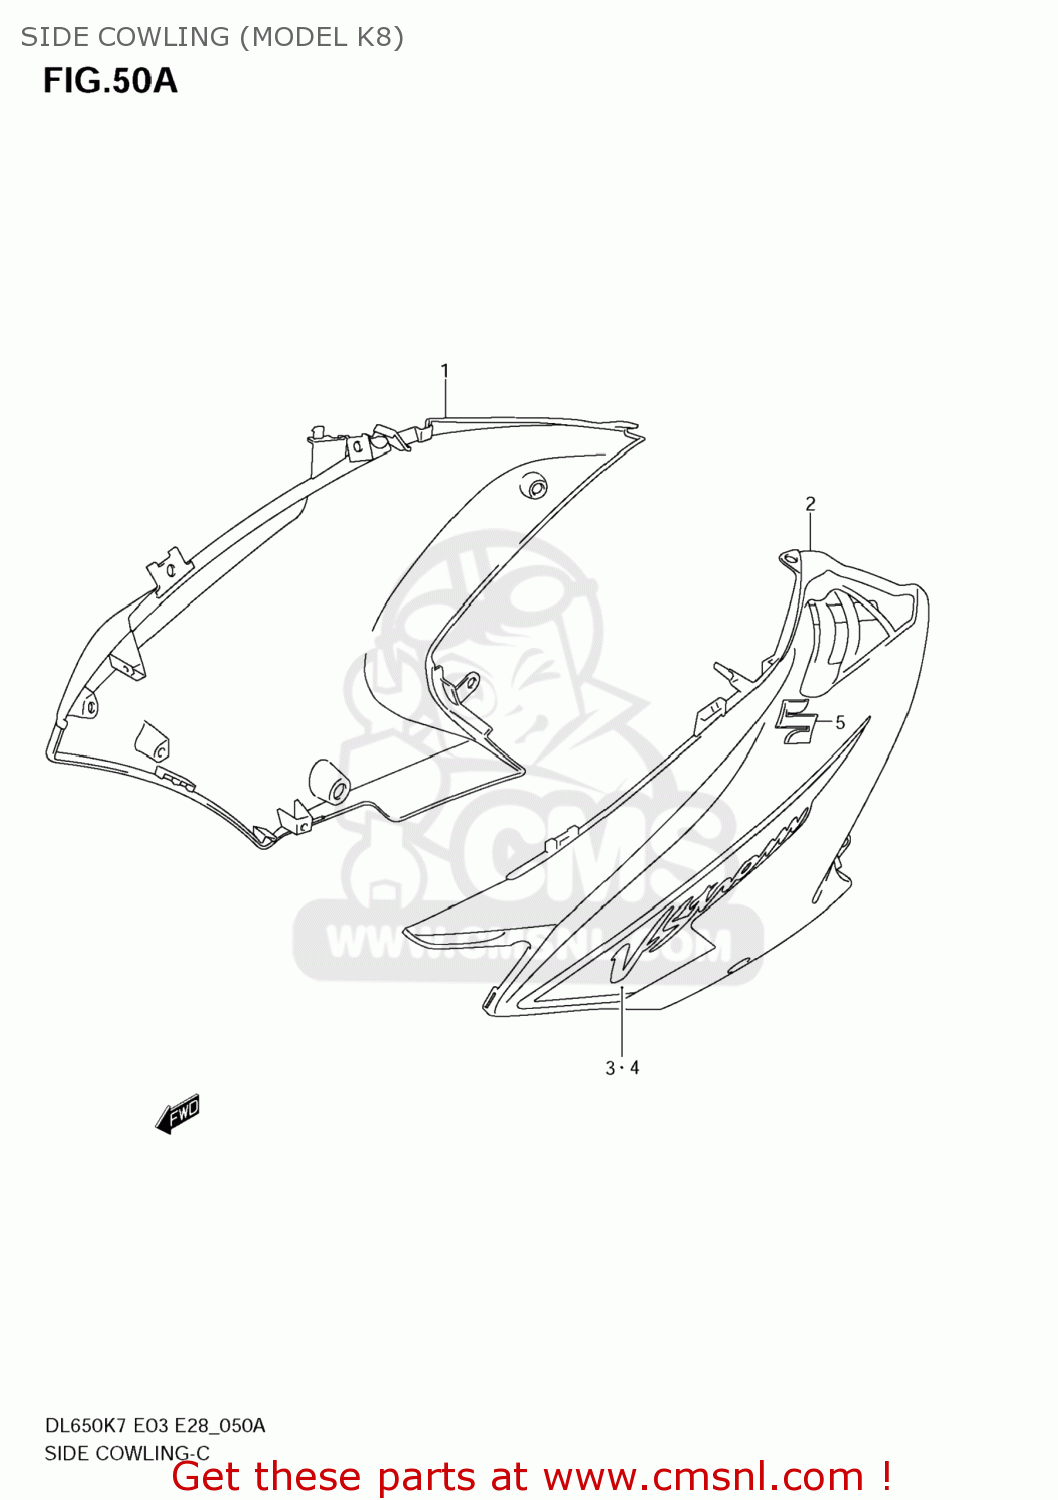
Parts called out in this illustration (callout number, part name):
1	COWLING ASSY,SIDE,R
2	COWLING ASSY,SIDE,L
3	TAPE,COWL SIDE,R
4	TAPE,COWL SIDE,L
5	EMBLEM,S
